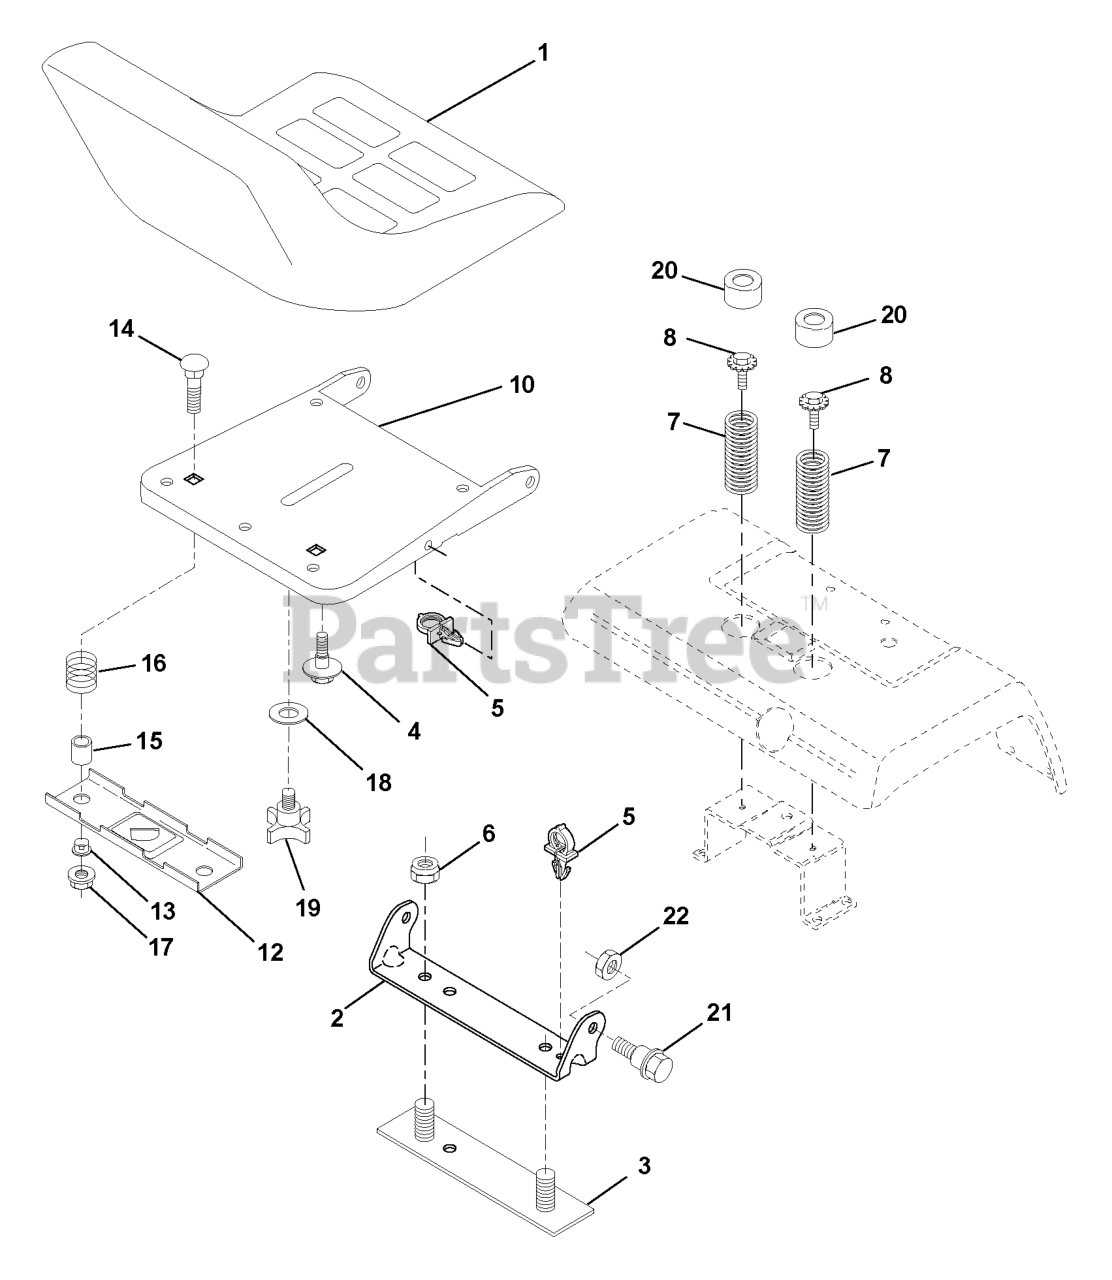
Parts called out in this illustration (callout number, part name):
1	SEAT
2	SEAT PIVOT BRKT
3	STRAP
4	BOLT,SHOULD
6	NUT
7	SPRING COMPRESSION
8	Screw, Thdrol 5/16-18 X 1/2
9	WASHER
10	SEAT PAN
12	BRKT SWITCH
14	Bolt, Carriage 1/4-20 X 1-3/8
15	SPACER SPLIT
16	SPRING COMPRESSED
17	NUT T
19	KNOB 1/2" YT
20	CAP SPRING
21	BOLT.SHOULDER.5/16-18
22	LOCKNUT
